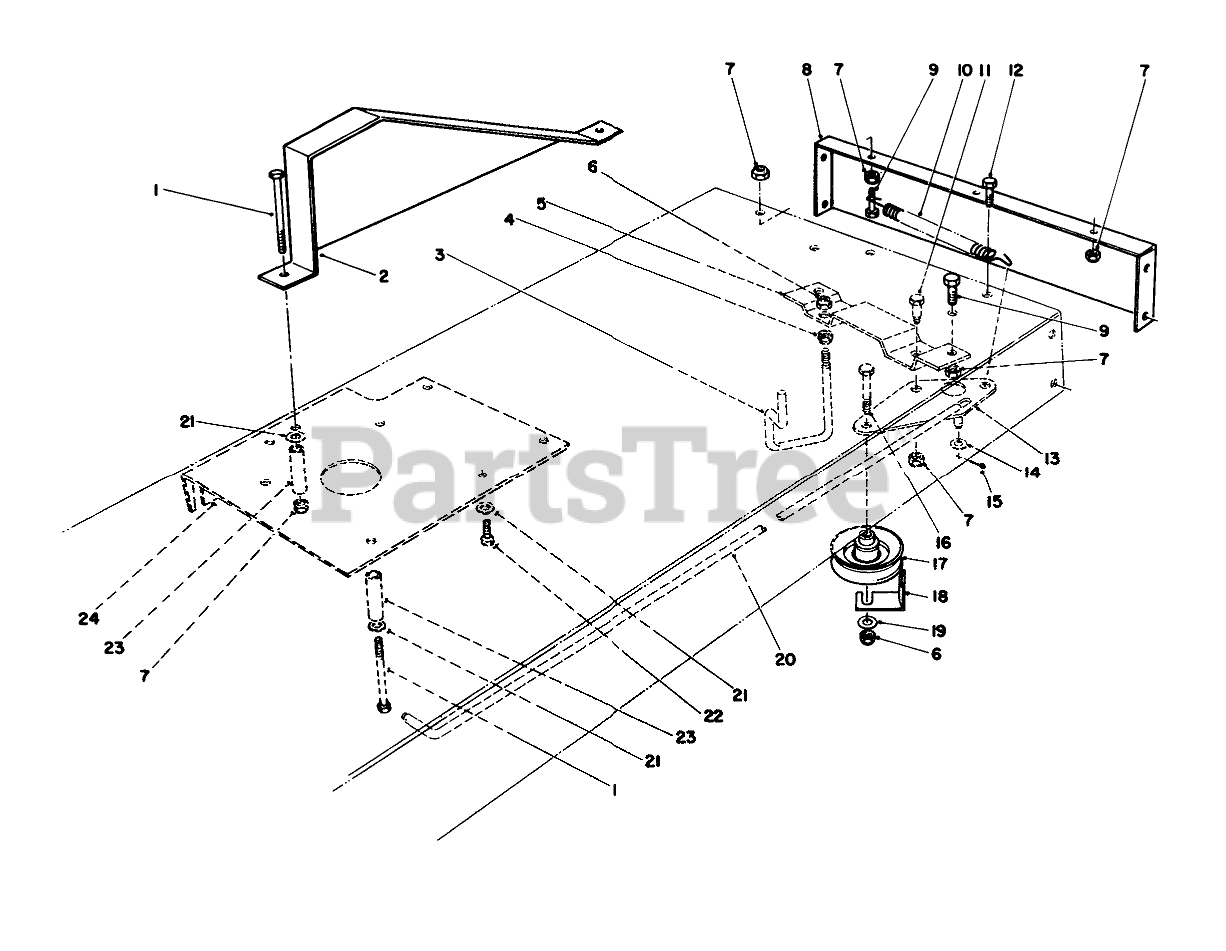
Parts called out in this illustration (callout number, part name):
1	SCREW-HH
2	CHAIN GUARD R
3	BELT GUIDE
4	NUT-LOCK, SIDE
5	TRACT SUPP BRKT B
6	NUT-LOCK, CONE
7	NUT-LOCK, NI
8	REAR FRAME R
9	SCREW-HH
10	TRACTION SPRING
11	BOLT-SHOULDER
12	SCREW-HH
13	TRACTION PIVOT BRKT
14	WASHER-FLAT
15	PIN-COTTER
16	SCREW-HH
17	PULLEY-IDLER
18	RETAINER-BELT
19	WASHER-FLAT
20	TRACTION ROD
21	WASHER-PLAIN
22	Screw-HH
23	OUTER TUBE SPACER
24	REINF PLATE R
